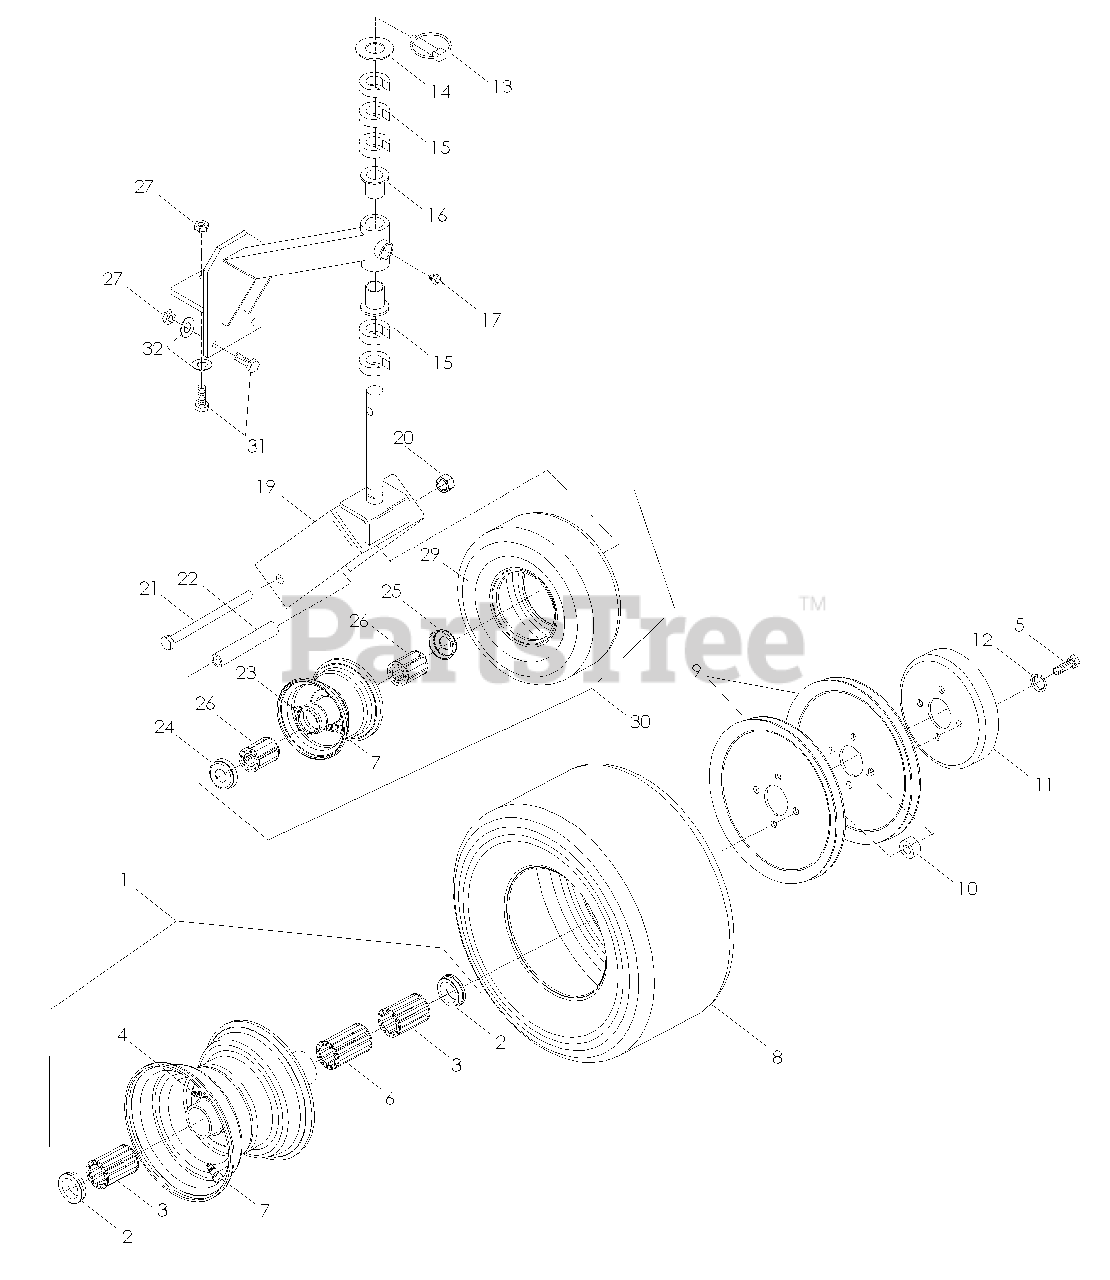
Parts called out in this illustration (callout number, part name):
1	WHEEL
2	BEARING, FLANGED
3	ROLLER BEARING, SHORT
4	ZERK 1/4-28 STRAIGHT
5	HCS 3/8-24 x 1 1/2
6	ROLLER BEARING
8	TIRE
9	TRACTION PULLEY
11	DRUM, BRAKE
12	LOCKWASHER 3/8
13	LYNCH PIN 7/16
16	BUSHING, FLANGED
17	CASTER ARM W/BUSHING
18	ZERK 1/8 NPT
19	CASTER YOKE
20	NUT 1/2-13 NYLOC
21	HCS 1/2-13 x 5 1/2
24	NOTCHED ENDCAP
25	ENDCAP
26	ROLLER BEARING
27	NUT 3/8-16 CNTRLK
30	TIRE & WHEEL COMPLETE
31	HCS 3/8-16 x 1
32	WASHER 3/8
32	FRONT WHEEL CASTER COMPLETE
